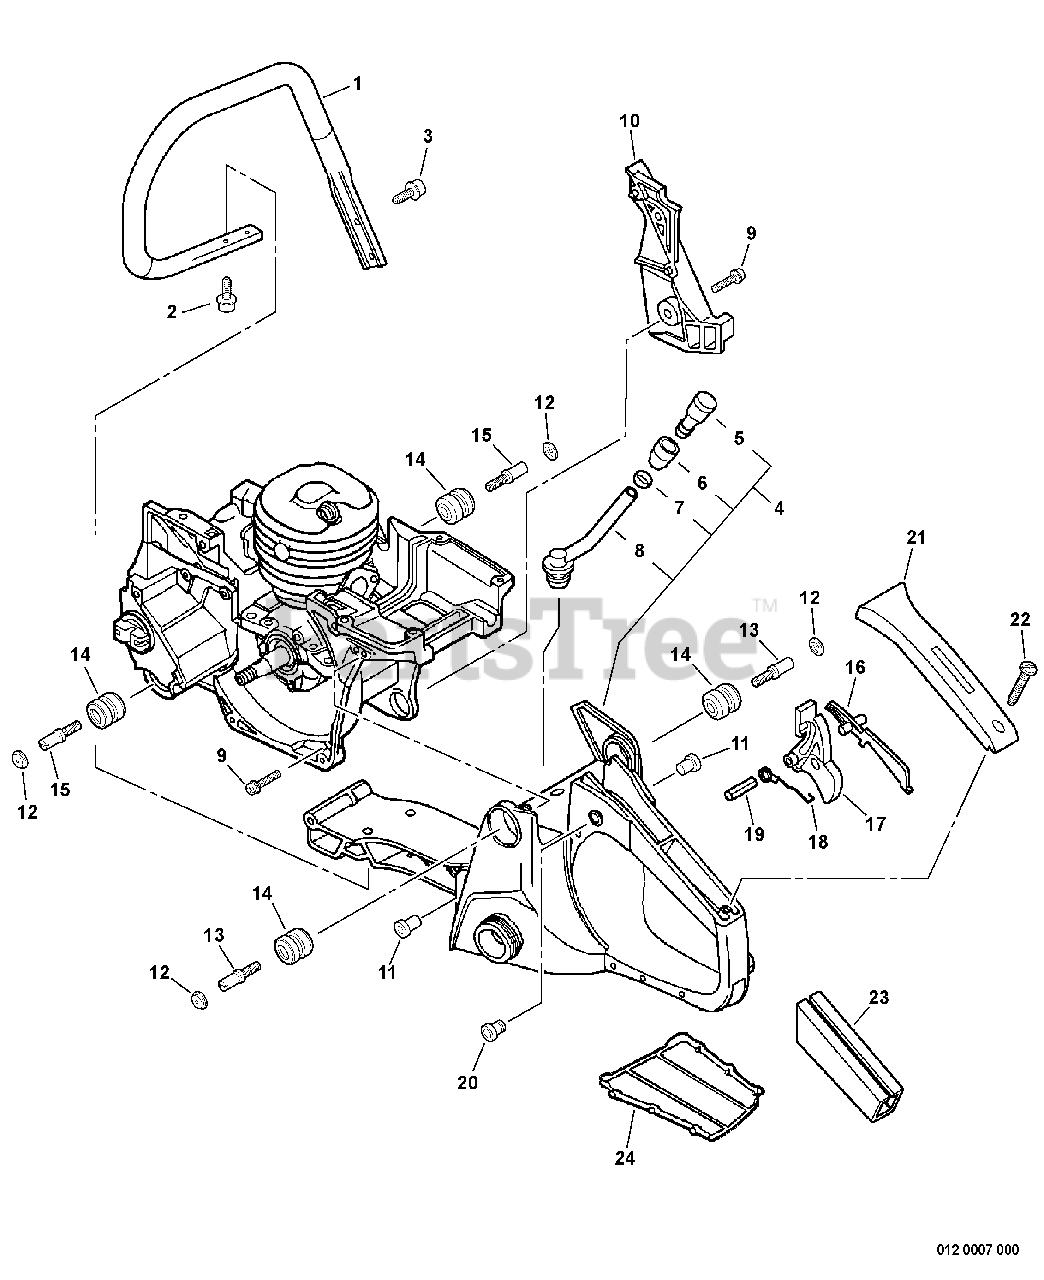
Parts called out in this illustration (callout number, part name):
1	HANDLE, FRONT
2	SCREW TAPPING 5×16
3	SCREW TAPPING 5×20
4	REAR HANDLE ASSY
5	VENT ASSY
6	HOLDER, VENT
7	CLIP Ø6.5 MM
8	PIPE, VENT - GROMMET
9	SCREW 5×16
11	CUSHION 5
12	CAP, CUSHION
14	CUSHION 5
16	LEVER, THROTTLE LOCKOUT
17	TRIGGER, THROTTLE
18	SPRING, THROTTLE RETURN
19	PIN, SPRING 4×30
21	COVER, HANDLE
22	SCREW 4×14
23	GRIP, HANDLE
24	SHIELD, SNOW
